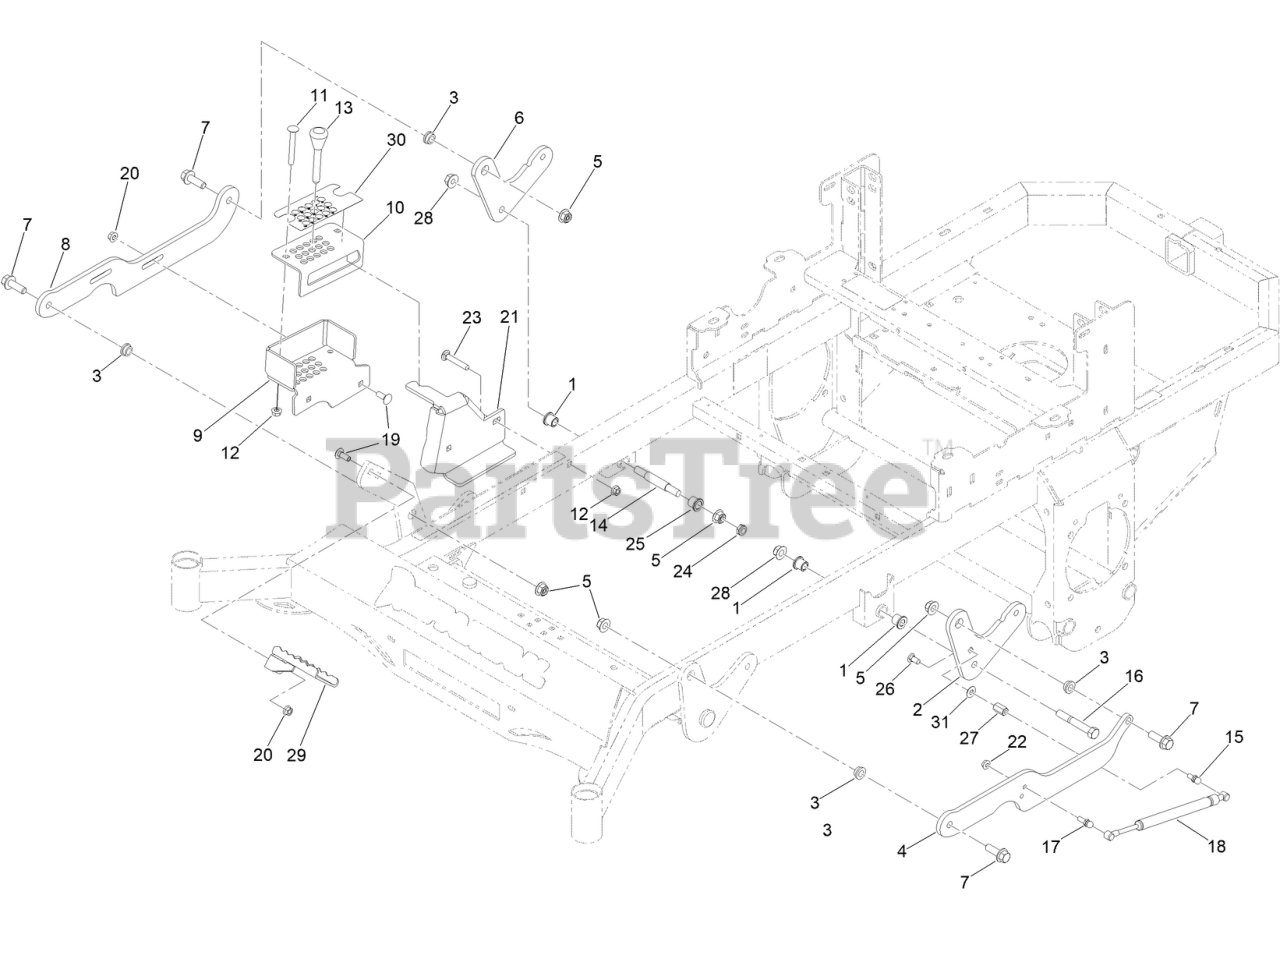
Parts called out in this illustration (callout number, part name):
1	BUSHING-FLANGE
2	ARM-DECKLIFT REAR (3/8")
3	1/2IN ID X 3/4IN OD X 3/8IN FLANGE BUSH
4	LINK-DECKLIFT
5	1/2-13 HEX FLANGE 2-WAY REV CNTR L/NYZ
6	ARM-DECKLIFT REAR (3/8")
7	SCREW-HHF
8	2024 DECK HEIGHT ARM RT LINK
9	BRACKET PIN SYSTEM (BOTTOM) PAINTED GREY
10	2022 DHI PIN ARM LINK TOP BRKT
11	(3/8-16 X 3 CARRIAGE BOLT (GR.5) ZC/YEL)
13	MAGNETIC PIN FOR STAND ON MWR
14	RR DECK HEIGHT BOLT (MACHINED)
15	5/16-18X1.286 DAMPER BALL STUD (.562 TL)
16	1/2-13 X 3-1/2 HEX C/S GR 5 ZINC YELLOW
17	5/16-18X1.286 DAMPER BALL STUD (.562 TL)
18	DECK ASSIST GAS SPRING
19	3/8-16 X 1 CARRIAGE BOLT YZ GR.8
20	3/8-16 HEX FLANGE NUT W/SERR ZINC YELLOW
21	2022 DECK LOCK PIN TUBE BRKT
23	SCREW-CARR
24	NUT-HEX
25	BUSHING-FLANGE
26	3/8 X 3/4IN GR 8 CARR BOLT ZINC
27	HEX COUPLING NUT - REDUCER (3/8" TO 5/16
28	NUT-HHF
29	MWR DECK HEIGHT FOOT PEDAL PAINT
30	DECAL-HEIGHT OF CUT
31	5/16IN USS FLAT WASHER (3/8 ID X 7/8 OD)
